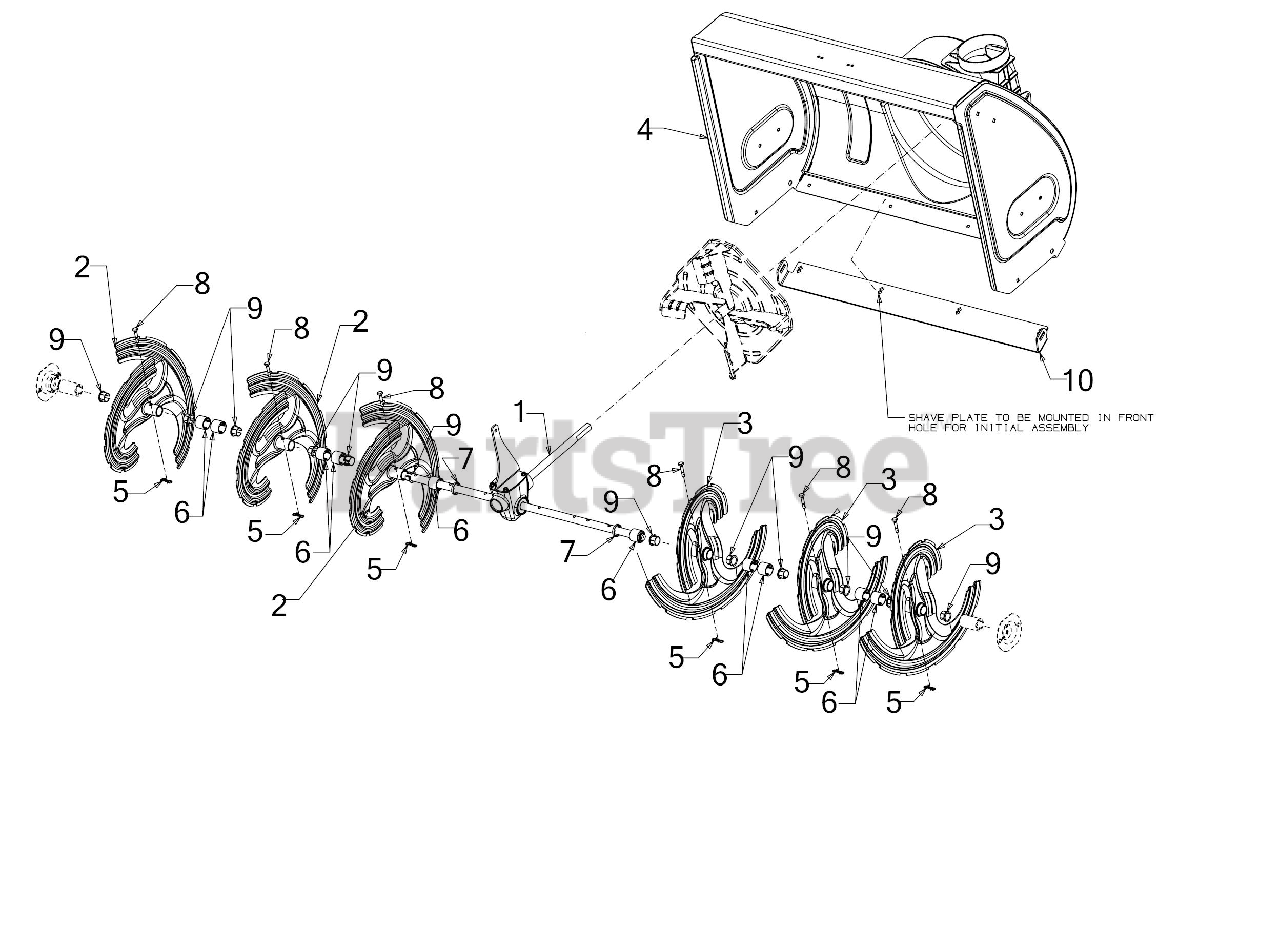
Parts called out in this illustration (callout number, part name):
1	34" AUGER GEARBOX ASSEMBLY
2	14" AUGER SPIRAL ASSEMBLY (RH)
3	14" AUGER SPIRAL ASSEMBLY (LH)
4	34" AUGER HOUSING ASSEMBLY
5	BOW TIE COTTER PIN 1/4-5/16
6	SPACER 1.25OD x .75ID X1.00 LG
7	SPCR 1.25 OD x 75IDX2.00LG
8	SHEAR PIN .25 x 1.50 GR2
9	FLANGE BUSHING
10	33.50" SHAVE PLATE
